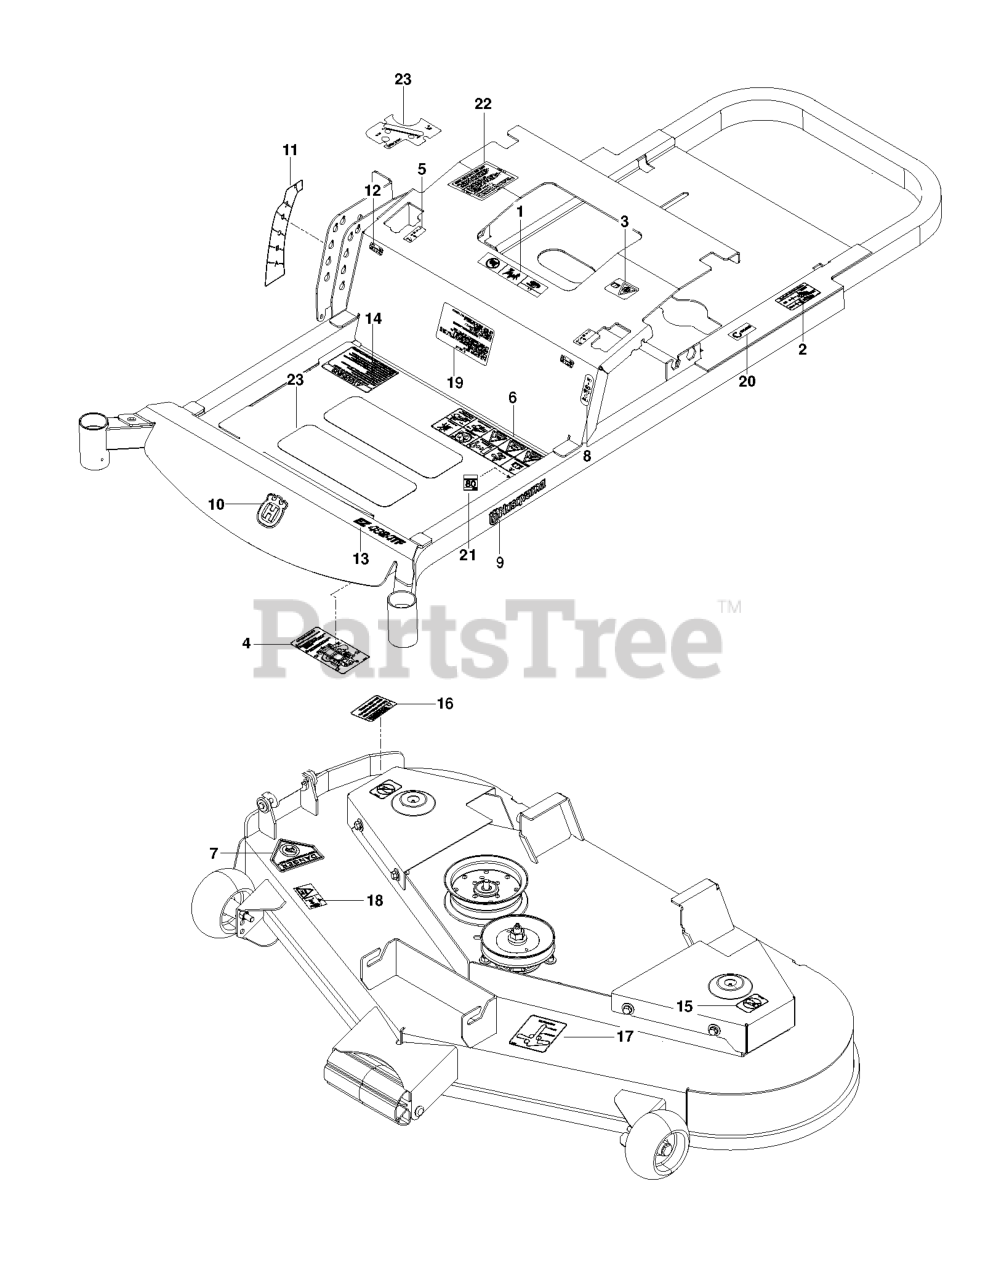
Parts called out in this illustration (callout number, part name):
1	EURO DECAL-BATTERY WARNIN6
2	DECAL, DO NOT TOW
3	DECAL, EXITING MOWER
4	DECAL, SERVICE
5	DECAL, MOTION CONTROL
6	DECAL, SAFETY WARNING
7	DECAL, CPSC
8	DECAL, PARK BRAKE
9	RP.DECAL.BADGE.170MM.TEXTLOGO
10	DECAL.AUGER.HUSQ.CROWN.SNOW
11	DECAL, DECK HEIGHT, HUSQ
12	DECAL, F.S.T.
13	DECAL MODEL EZ 4824TF
14	DECAL, WARNING
15	DECAL, NO STEP
16	DECAL, CAUTION
17	DECAL, BELT ROUTING
18	DECAL, EURO SEVERING
19	DECAL, START
20	DECAL, ECM, AUSTRALIA
21	DECAL 80 DBA
22	DECAL, CUSTOMER RESPNSIBILITY
23	DECAL, CTRL PANEL, HUSQ
24	ANTI-SKID PAD
